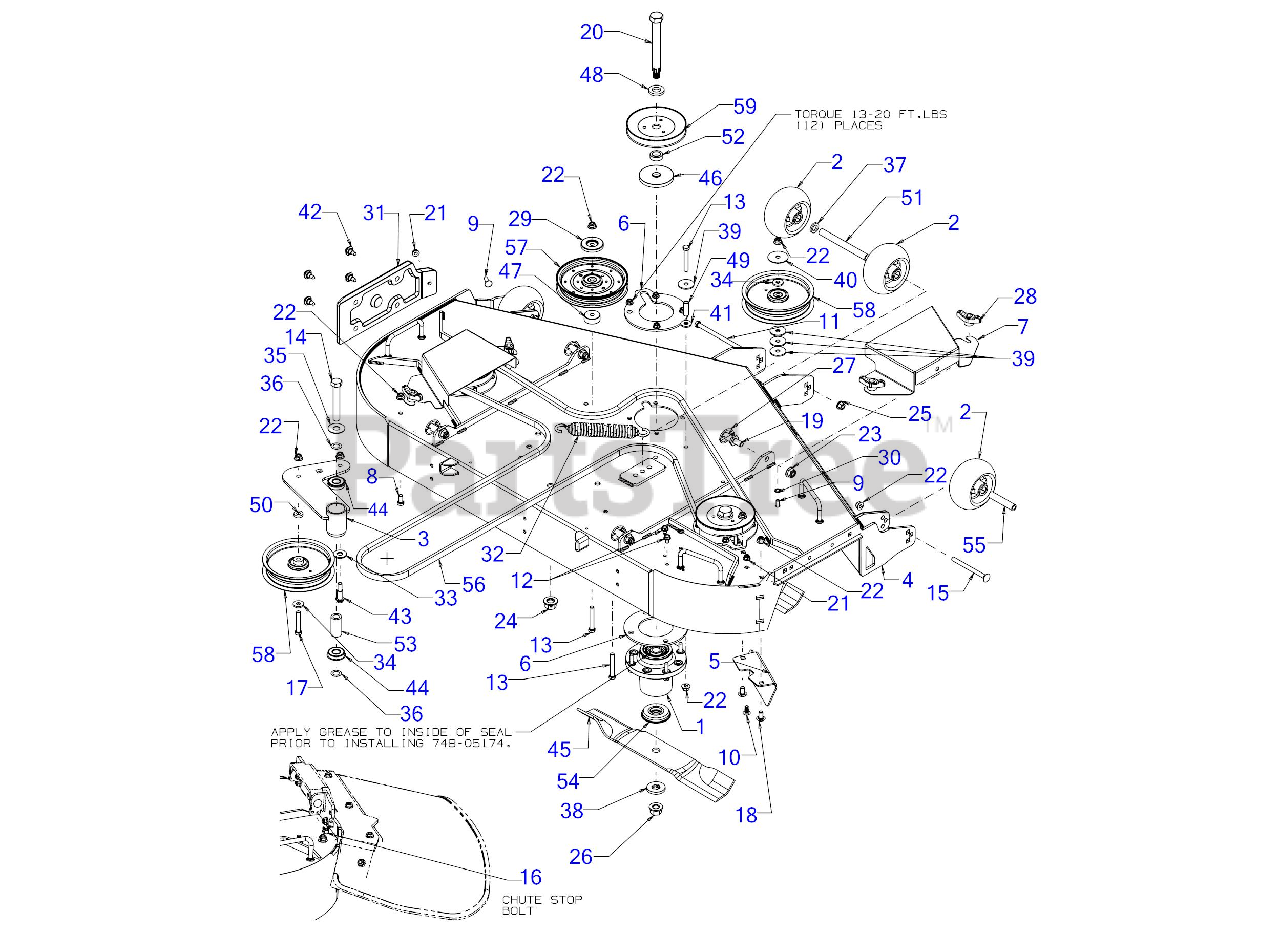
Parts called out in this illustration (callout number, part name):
1	SPINDLE ASSEMBLY
2	5" DIA DECK WHEEL COMPLETE
3	IDLER ARM ASSEMBLY
4	54" FAB DECK ASSEMBLY
8	HEX SCREW 3/8-16 x .75
9	CARRIAGE BOLT 5/16-18 x 1.00
10	CARRIAGE BOLT 5/16-18 x .75
11	SCREW 3/8-16 x 7.25 GR5
12	SCREW 5/16-18 x .500
13	HEX SCREW-3/8-16X2.5 GR5
14	SCREW 5/8-18 x 4 GR5
15	CARRIAGE BOLT 3/8-16 x 4.25 GR5
16	SCREW 1/4-20X.625
17	SCREW 3/8-16 x 2.25 GR5
18	CARRIAGE BOLT 3/8-16 x .75
20	SPINDLE SHAFT
21	FLANGE LOCK NUT 5/16-18
25	NUT-CTRLCK FLG HEX
26	FLANGE NUT - 5/8-18 GDE 8
28	WING KNOB 5/16-18
29	PULLEY CAP
31	DECK SKID PLATE (LH)
32	SPRING 1.25" DIA X 8.5" LONG
33	FLAT WASHER
34	FLAT WASHER .385 x 1.00 x .135
35	FLAT WASHER-.63IDX1.595ODX.62
36	FLAT WASHER
37	FLAT WASHER .632X1.00X.16
38	FLAT WASHER - SPECIAL
39	FLAT WASHER .406X1.500X.105
40	HUB CAP WASHER .406 x 1.92 x .060
41	FLAT WASHER .406ID X1.0 OD
42	SHOULDER SCREW .43X.29X5/16-18 TT
43	SHOULDER SCREW .50X.925
44	BALL BEARING
45	19" BLADE (HI LIFT)
45	Cub Cadet 54" HI LIFT BLADE SET
45	LOW-LIFT 19"BLADE (54"DECK)
45	BLADE- HI LIFT 19.0 XTREME
45	BLADE-19"MULCH 54"
45	19" XTREME BLADE
46	DECK SPINDLE SPACER
47	SPACER - .385 ID x 1.500DX .585 L
48	SPACER .812 ID x .218 LG
51	WHEEL SPACER
52	SPACER (.792 X 1.20 X .380)
53	SPACER 0.63 X 1.00 X 2.01
54	SPACER 0.790 X 2.75 X 0.486
55	WHEEL SPACER .38ID x 3.04LG
56	DECK BELT B SEC x 154
57	IDLER PULLEY
58	IDLER PULLEY (6.00" DIA)
59	SPINDLE PULLEY (5.625")
